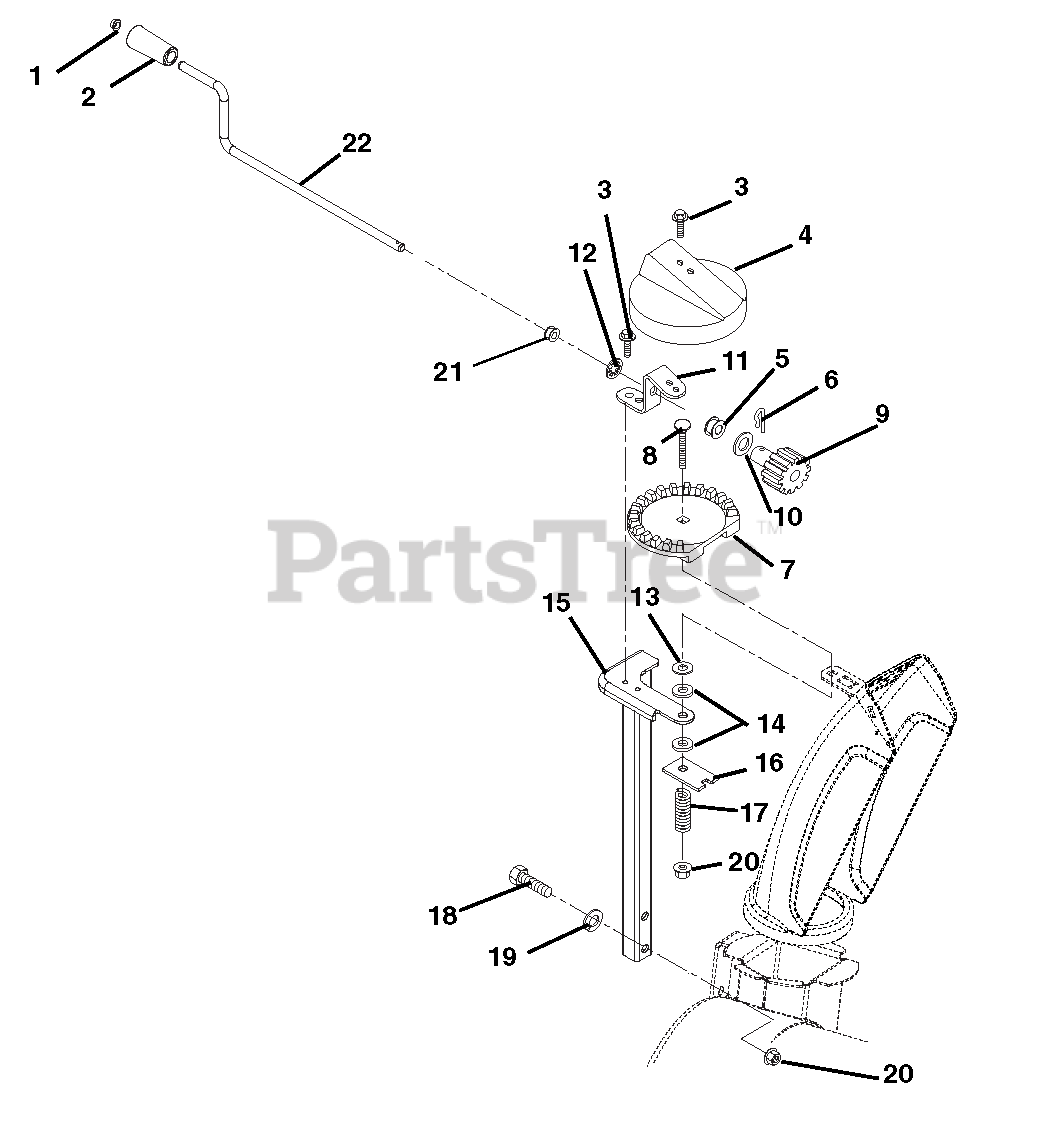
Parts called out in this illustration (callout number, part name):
1	CAP, 3/8 ROD YWZC
2	KNOB, CHUTE CRANK
3	SCR-TAP .25-20X.50 HWH TR YWZ
4	GEAR COVER
5	BUSHING, POLYLINER-.63 SNAPIN
6	PIN, SPRING CLIP
7	CHUTE GEAR
8	@BLT-RDHDSQNK .38-16X2.50 G5YZ
9	PINION GEAR W/BRACKET
10	WSHR-THRST .625 X 1.0 X .03
11	BRACKET, PINION GEAR
12	PUSHNUT .625
13	WSHR-FL-STL .380X1.50X.062 YWZ
14	FRICTION WASHER
15	CHUTE PEDESTAL, TALL COMPACT
16	PLATE, FRICTION
17	SG-COMP .187X.56X1.62
18	@BLT-HEX .38-16X1.75 GR5 YWZC
19	@WSHR-LK .38X.094 REG YWZC
20	@NUT-LK-TOP-FLG .38-16 YWZC
21	BUSHING, POLYLINER-.38 SNAPIN
22	CHUTE CRANK,COMPACT 920,XXX HI
